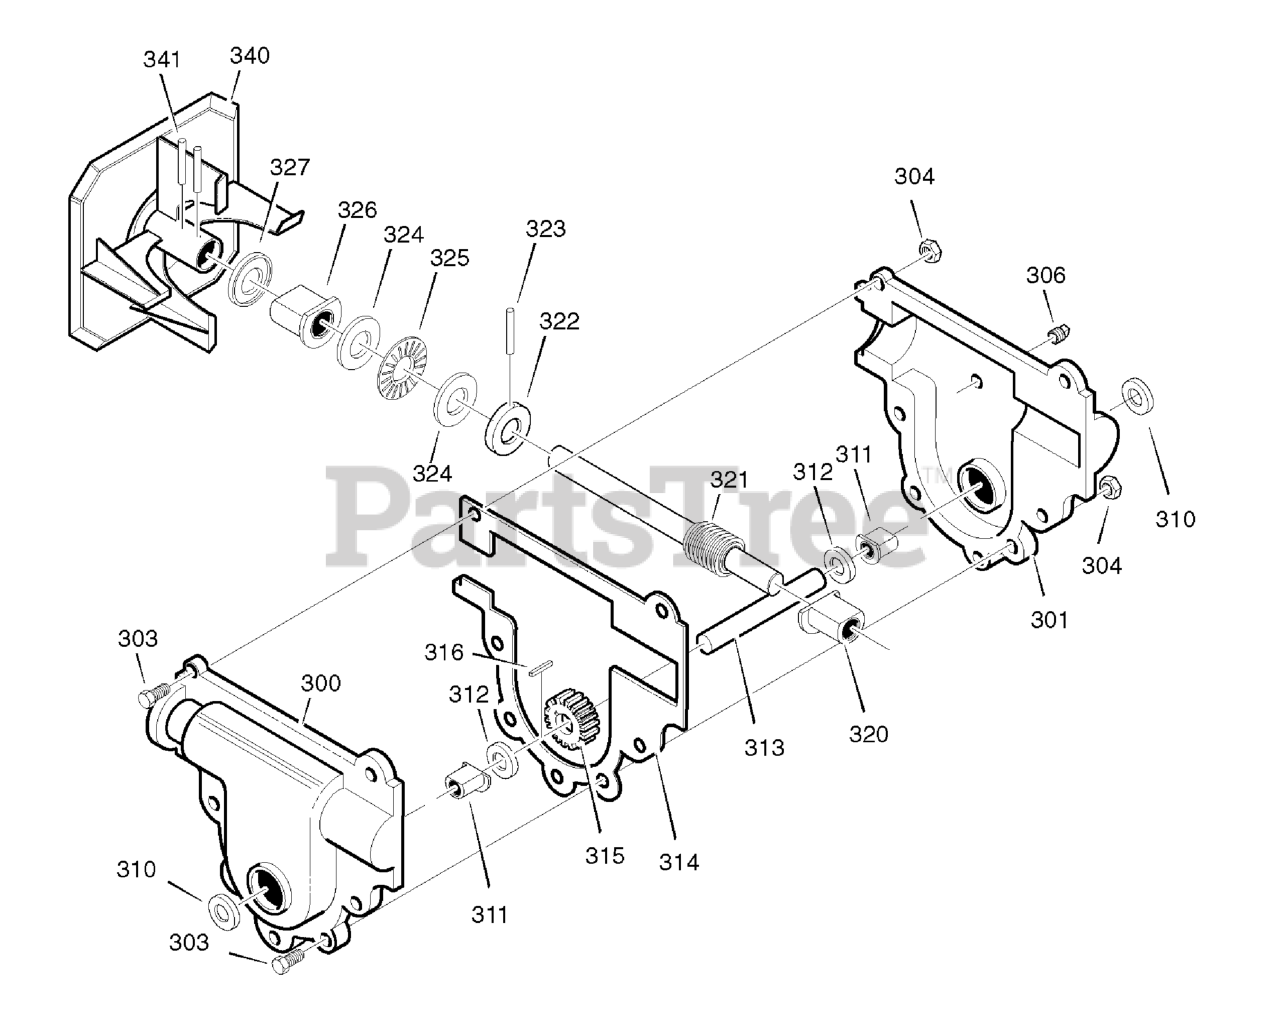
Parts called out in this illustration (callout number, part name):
300	CASE, GEAR, RH
301	CASE, GEAR, LH
303	SCREW, 1/4-20 X .75
304	NUT,1/4-20
306	SCREW, 3/8-16 X .50
310	SEAL, OIL
311	BEARING, FL
312	WASHER, FLAT
313	SHAFT, AUGER OUTPUT
314	GASKET, GEAR BOX
315	GEAR, WORM
316	KEY, WOODRUFF #61
320	FLANGE BEARING
321	SHAFT, AUGER INPUT
322	COLLAR, THRUST
323	PIN, SPRING
324	WASHER, FLAT
325	BEARING, ROLL
326	BEARING, FLANGE
327	SEAL, OIL
340	IMPELLER
341	PIN, SPRING
